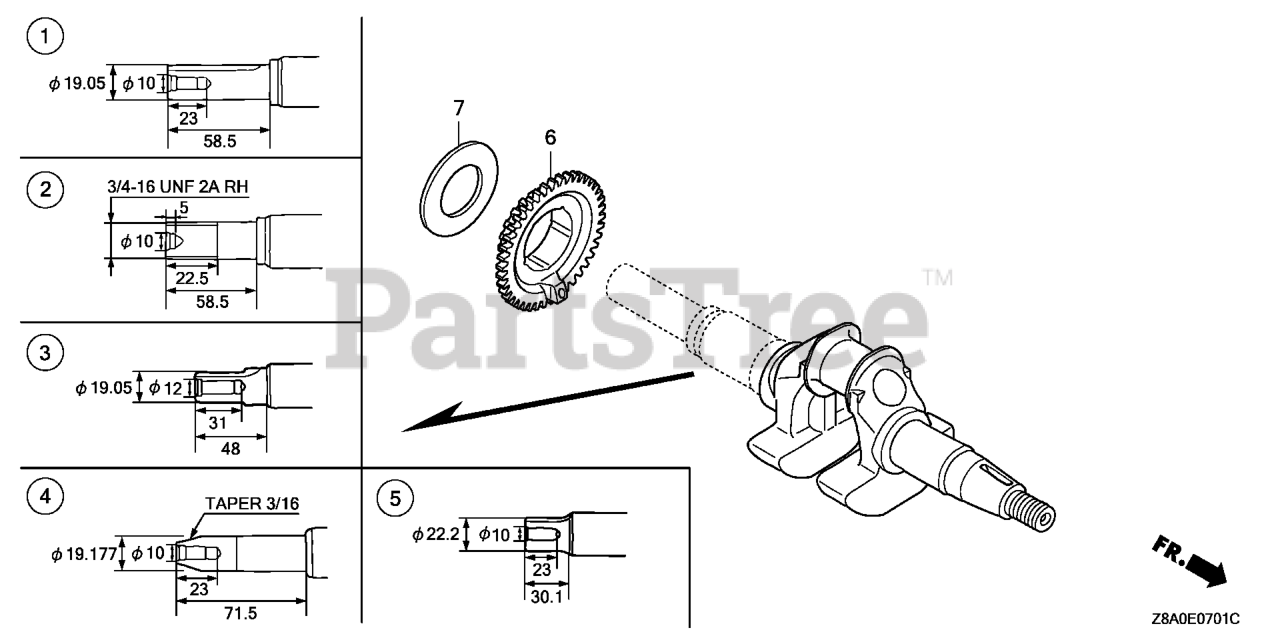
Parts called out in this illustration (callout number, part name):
1	CRANKSHAFT
6	PULLEY, TIMING BELT DRIVE
7	WASHER, THRUST
